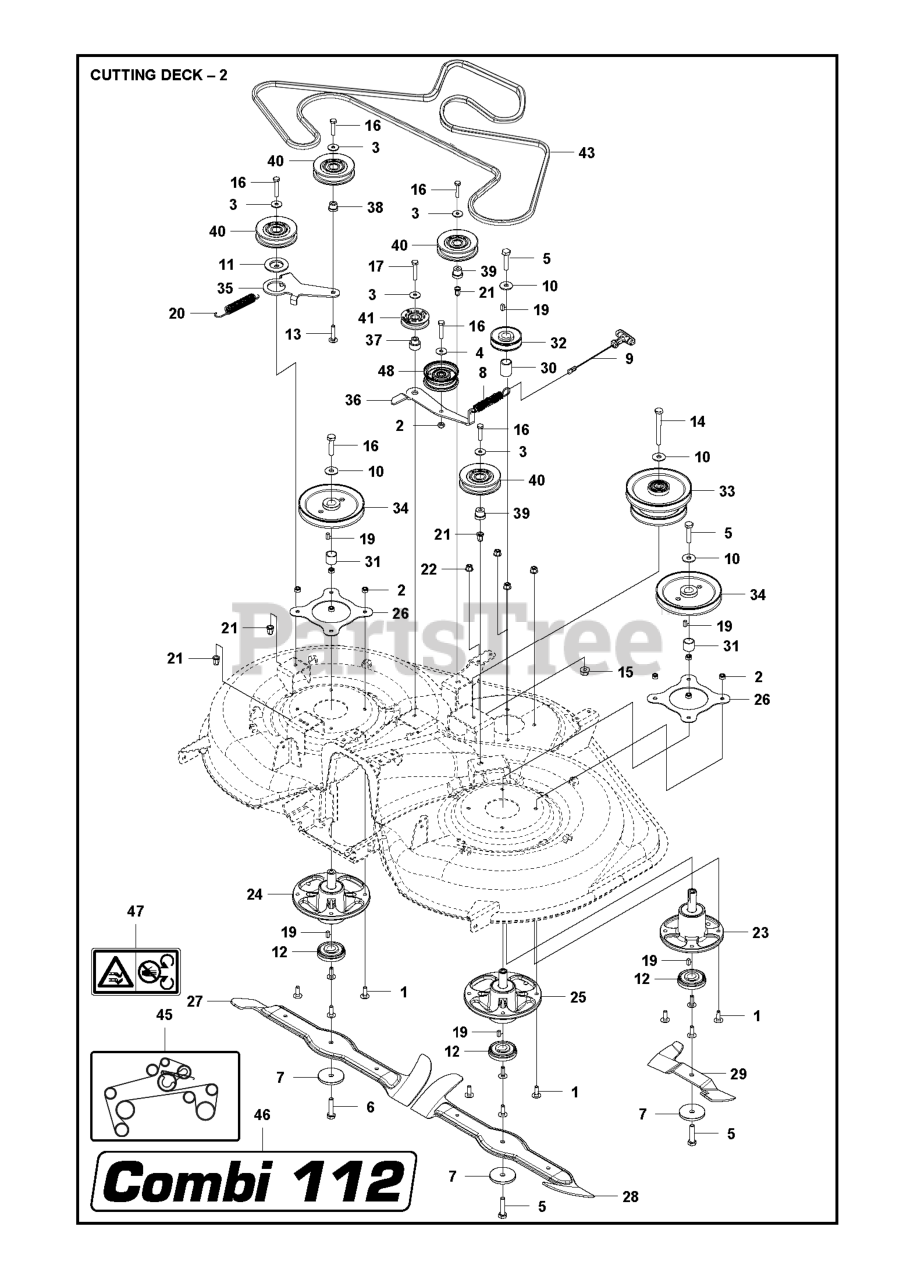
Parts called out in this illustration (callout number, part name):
2	LOCKNUT M8
13	Screw Mvbf 8 X 40
17	SCREW
21	BLIND RIVET NUT
22	NUT FLANGE
48	IDLER PULLEY
